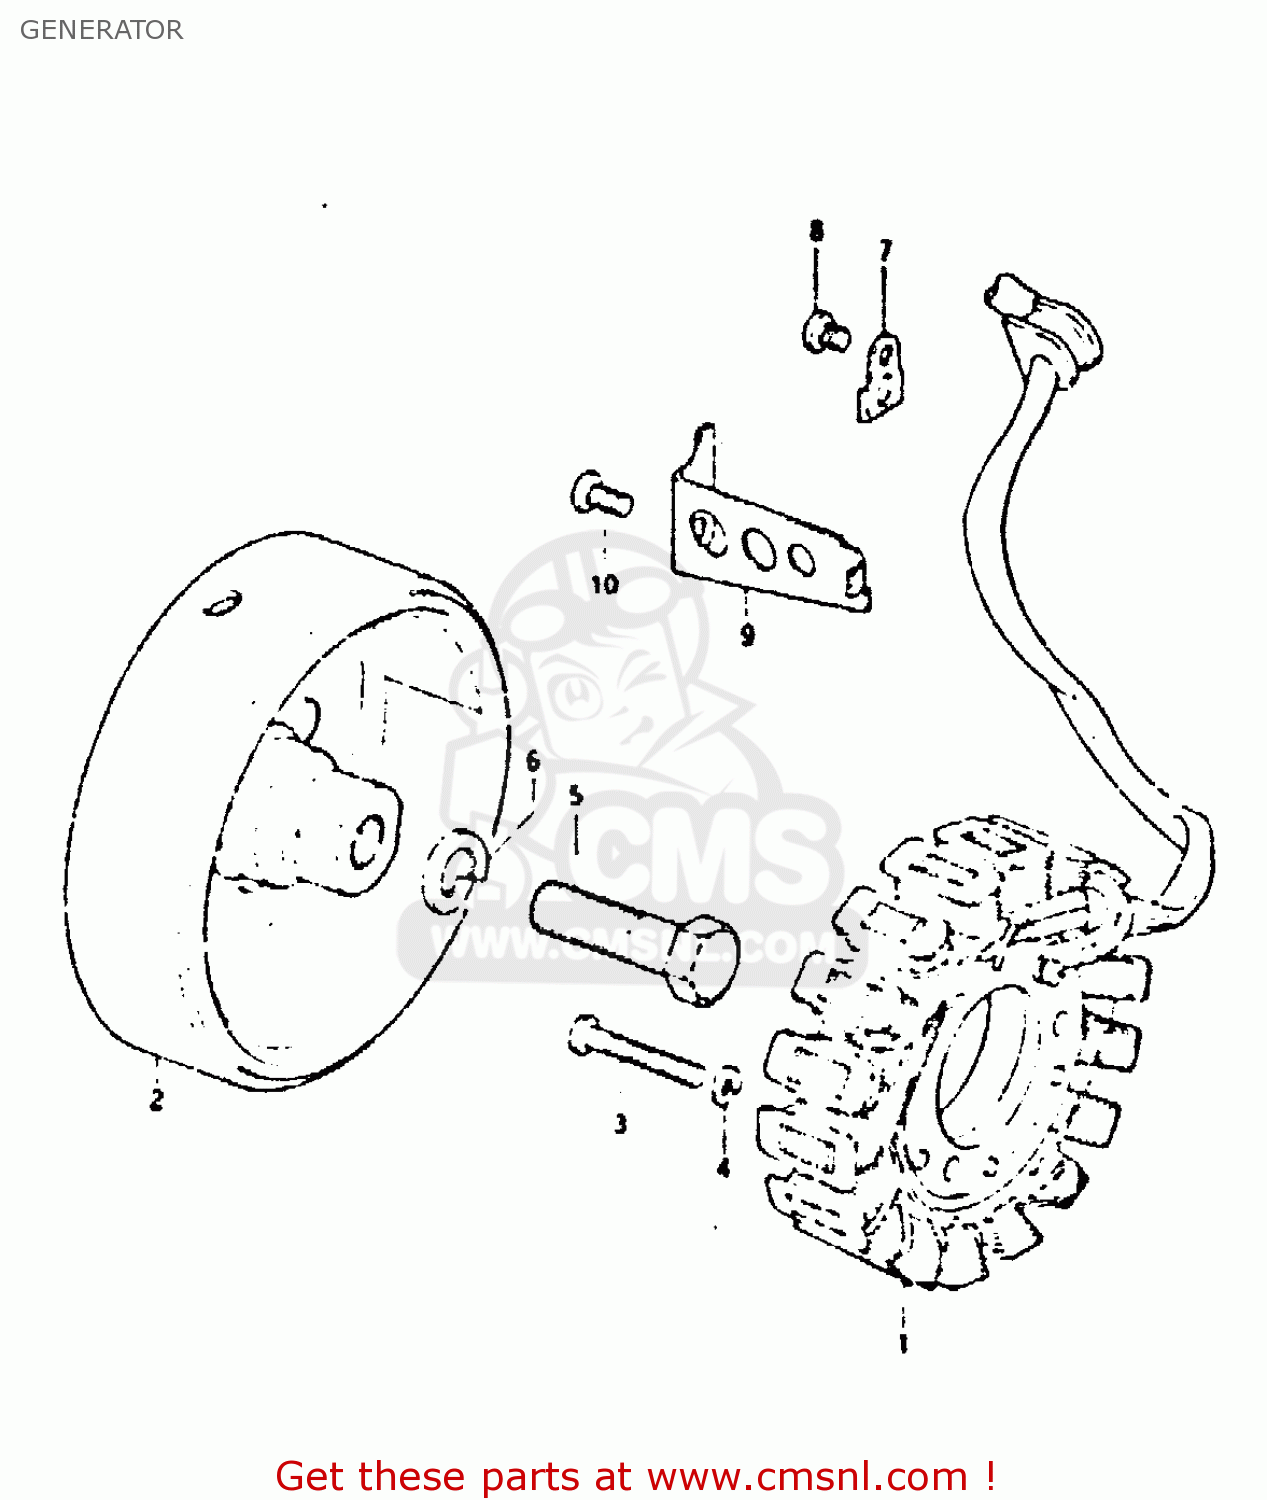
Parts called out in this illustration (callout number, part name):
1	STATOR ASSEMBLY
2	ROTOR ASSEMBLY
3	SCREW
4	LOCK WASHER
5	BOLT 12X45
6	WASHER,LOCK 12
7	CLAMP,GENERATOR LEAD WIRE
8	SCREW
9	CLAMP,GENERATOR LEAD WIRE
10	SCREW
